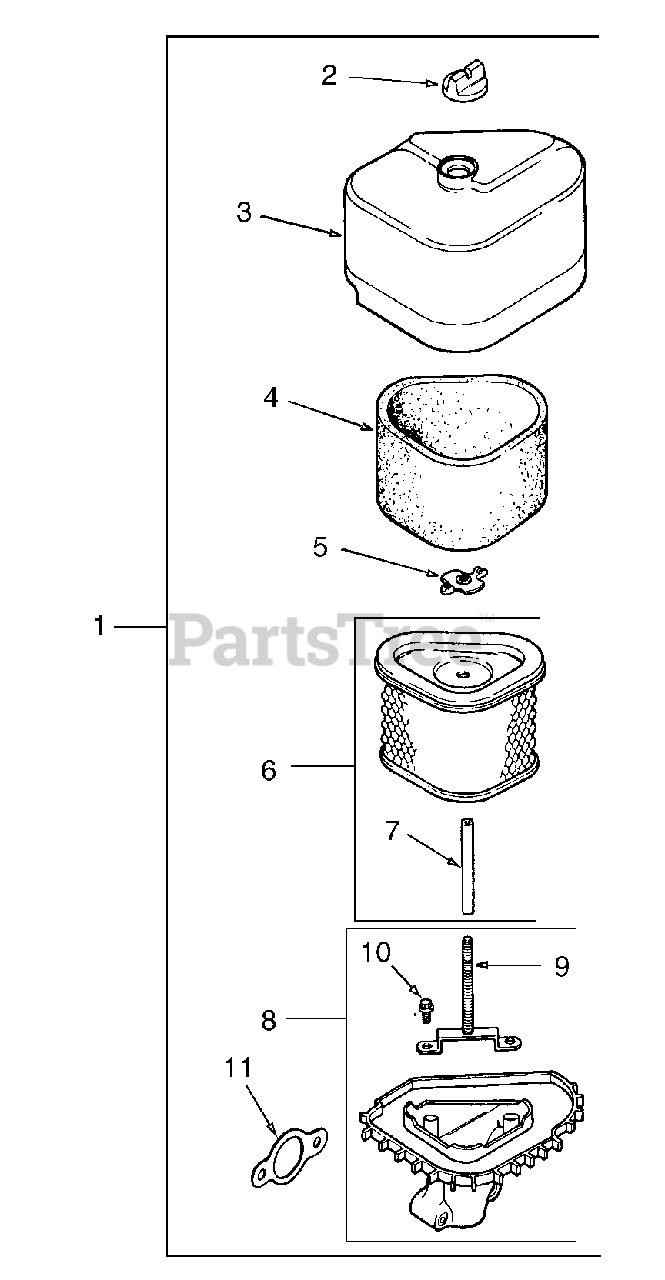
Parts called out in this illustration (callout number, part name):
1	Kit, Air Cleaner
2	Knob, Air Cleaner Cover
3	Cover, Air Cleaner
4	Element, Precleaner
6	Element, Air Cleaner
8	Base, Air Cleaner
9	Stud, M6 x 1.0 x 66
10	Screw, #1 Hi-Lo Thread Forming
11	Gasket, Air Cleaner
